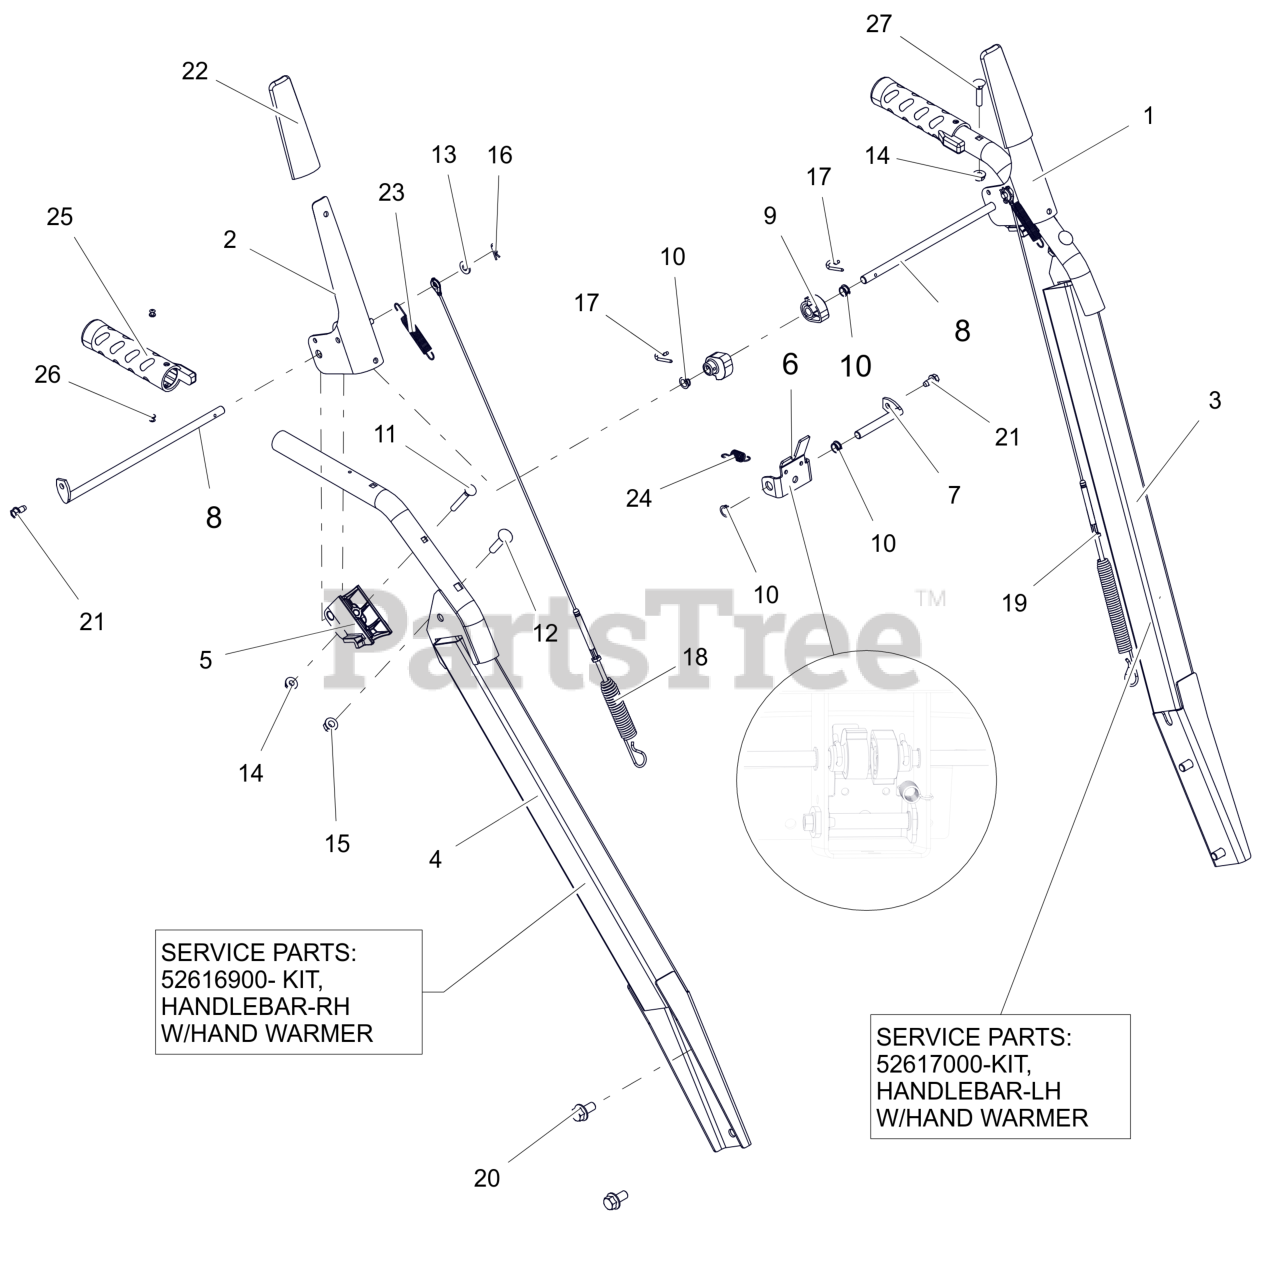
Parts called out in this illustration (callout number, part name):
1	LEVER, CLUTCH-LH
2	LEVER, CLUTCH-RH
3	HANDLEBAR, HEAVYDUTY-PRO LH
3	KIT, HANDLEBAR-LH W/WARM GRIP
4	HANDLEBAR, HEAVYDUTY-PRO-RH
4	KIT, HANDLEBAR-RH W/WARM GRIP
5	BLOCK, CLUTCH PADDLE
6	BRACKET, INTERLOCK ARM
7	ROD, PIVOT - INTERLOCK
8	ROD, PADDLE MOUNT - PRO
9	CAM, INTERLOCK
10	BUSHING, POLYLINER-.38 SNAPIN
11	BLT-RDHDXLSQNK .25-20X2.0 G5YZ
12	BLT,RHSN .31-18X1.50 G5 ZCC
13	WSHR,FLT .281X.625X.065 ZCC
14	NUT-LK-CTR-FLG .25-20 ZC120
15	NUT-LK-TOP-FLG .312-18 GF ZCC
16	PIN, HAIR #178 .06X.77 ZCC
17	PIN, SPRING CLIP
18	CABLE, AUGER (DELUXE & PRO)
19	CABLE, UPPER TRACTION
21	SCR-TAP .25-20X.50 HWH ZCC
22	COVER, PADDLE
23	SPRING, EXTENSION
24	SPRING-EXT .047X.438X1.45
25	GRIP, HANDLE - HEATED
26	RVT-POP #43 .125X.313 STL ZINC
27	BLT-RDHDXLSQNK.25-20X1.25 G5ZC
